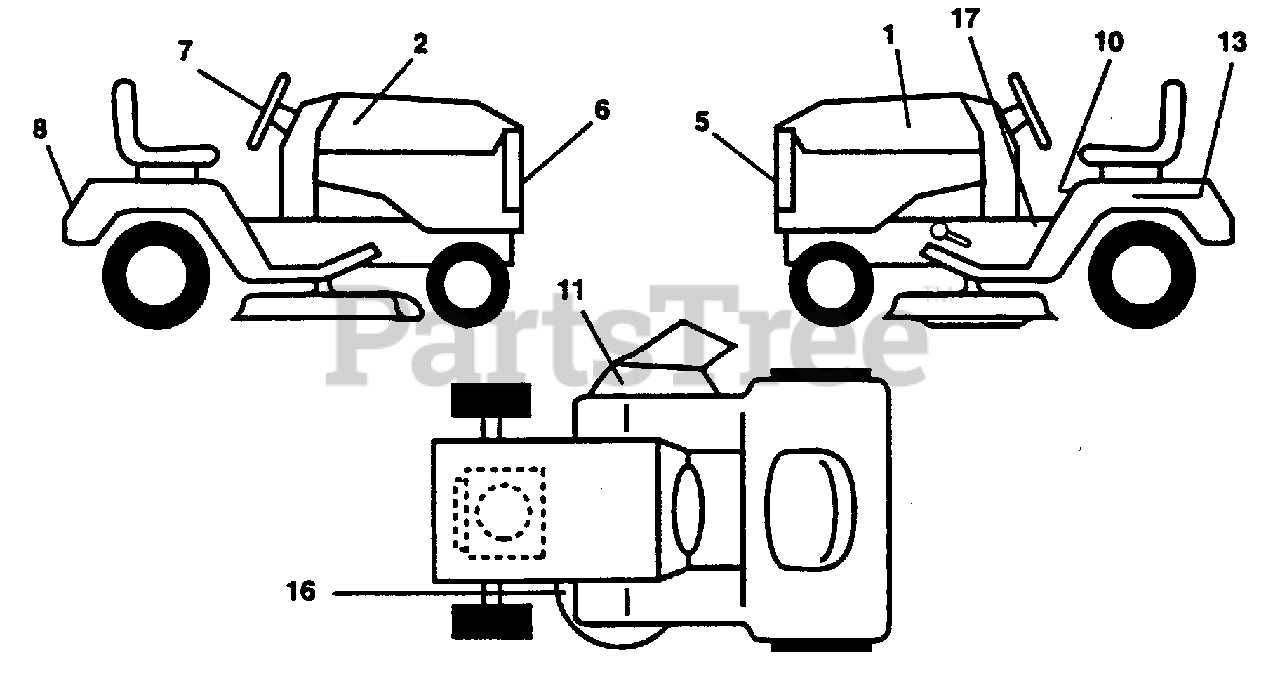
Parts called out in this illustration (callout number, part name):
1	Decal, Hood, L. H.
2	Decal, Hood, R. H.
5	Decal, Grill
6	Decal, Lightbox (AYP part number)
7	Decal, Insert, Stg. Whl.
8	Decal, Fender (AYP part number)
10	Decal, Caution, Fender (AYP part number)
11	Decal, Warning, Cut Finger, (Multi-Lang) (AYP part number)
13	Decal, Caution, Battery (AYP part number)
16	Decal, V-Belt Sch. (AYP part number)
17	Decal, Inst. Oper. (AYP part number)
